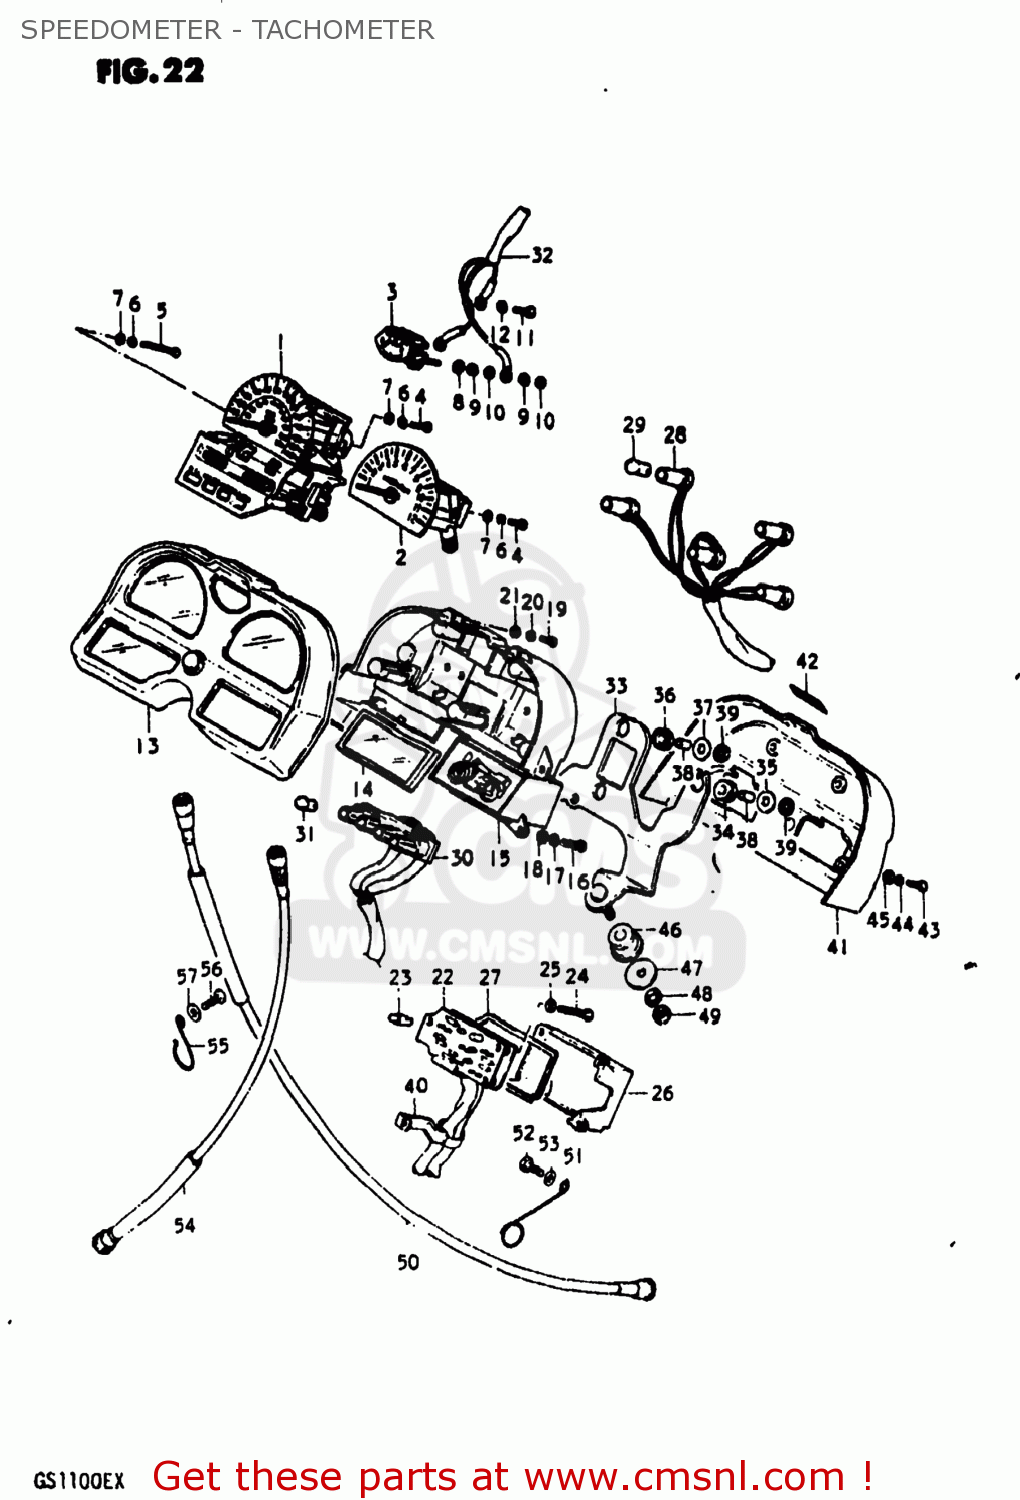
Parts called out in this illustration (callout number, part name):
2	TACHOMETER
3	FUEL METER
4	SCREW
5	SCREW
6	LOCK WASHER
7	WASHER
8	WASHER
9	LOCK WASHER
10	NUT 4MM
11	SCREW
12	LOCK WASHER
13	HOOD, METER
14	GLASS, CHECK PANEL
15	CASE
16	SCREW
17	LOCK WASHER
18	WASHER
19	SCREW 3X12
20	LOCK WASHER
21	WASHER
22	CHECK PANEL UNIT
23	BULB
24	SCREW
25	LOCK WASHER
26	LOWER CASE, CHECK PANEL
27	GASKET
28	SOCKET, METER
29	BULB(12V3.4W,STANLEY,A72A)
30	SOCKET, PILOT LAMP
31	BULB(12V3.4W,STANLEY,A72A)
32	LEAD WIRE, FUEL METER
33	BRACKET
34	CUSHION
35	WASHER,METER
36	CUSHION (B)
37	WASHER (B)
38	SPACER
39	NUT
40	CLAMP
41	COVER, LOWER
42	EMBLEM
43	SCREW
44	LOCK WASHER
45	WASHER
46	CUSHION,METER
47	WASHER (8.5X29X1.6)
48	LOCK WASHER
49	NUT
50	CABLE ASSEMBLY,SPEEDOMETER
51	GUIDE,SPEEDOMETER CABLE
52	BOLT, UPPER
53	WASHER
54	CABLE ASSEMBLY,TACHOMETER
55	GUIDE,WIRING HARNESS
56	SCREW 6X12
57	WASHER
